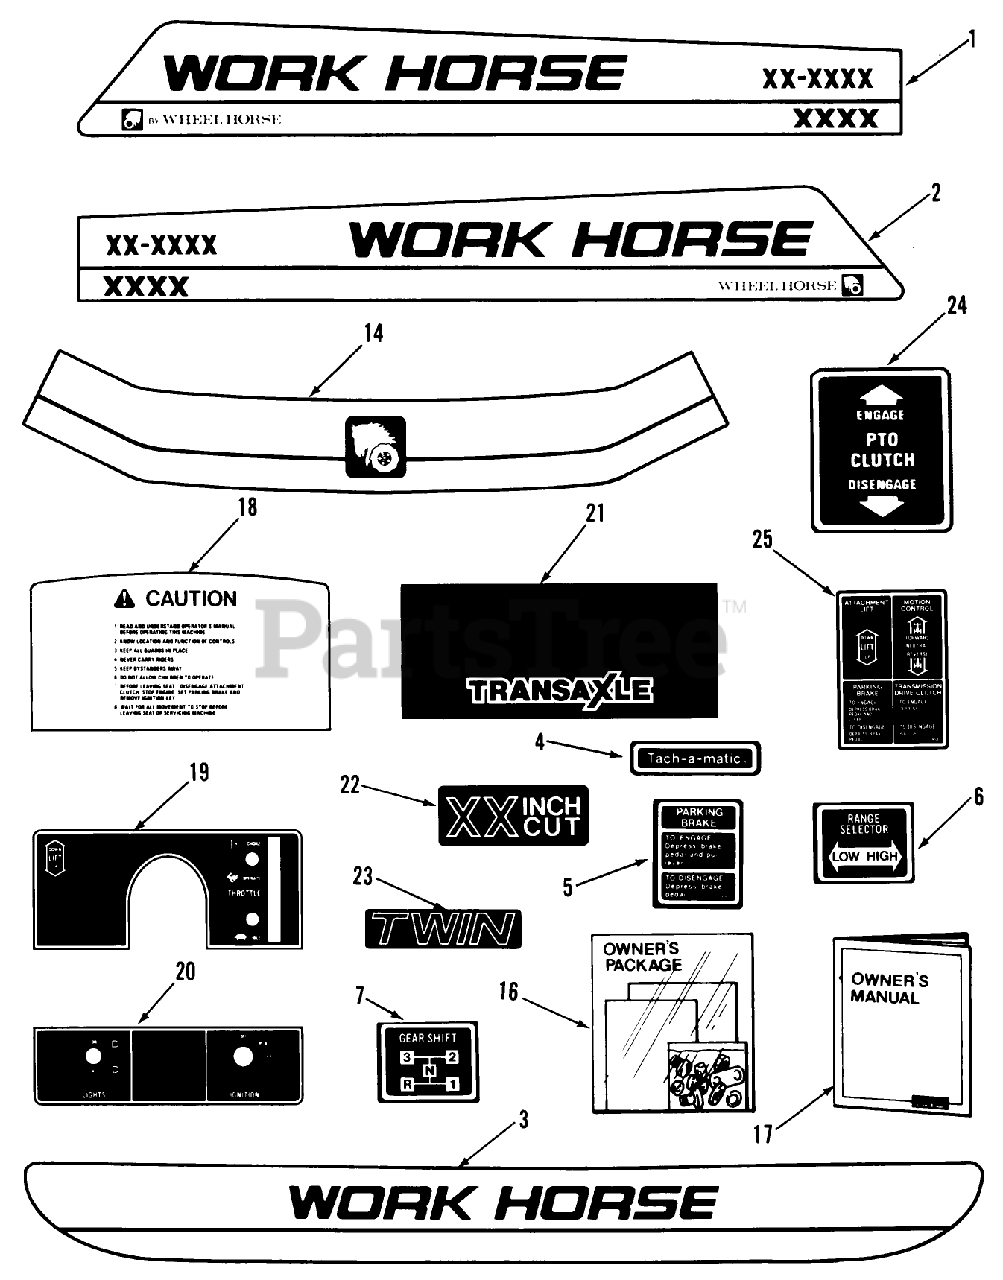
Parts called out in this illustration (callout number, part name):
5	DECAL-PARKING BRAKE
6	DECAL, RANGE SELECTOR
16	Loose Parts Package GT-1642, GT-1848 Only
16	Loose Parts Package GT-1142 Only
17	Owner-s Manual
